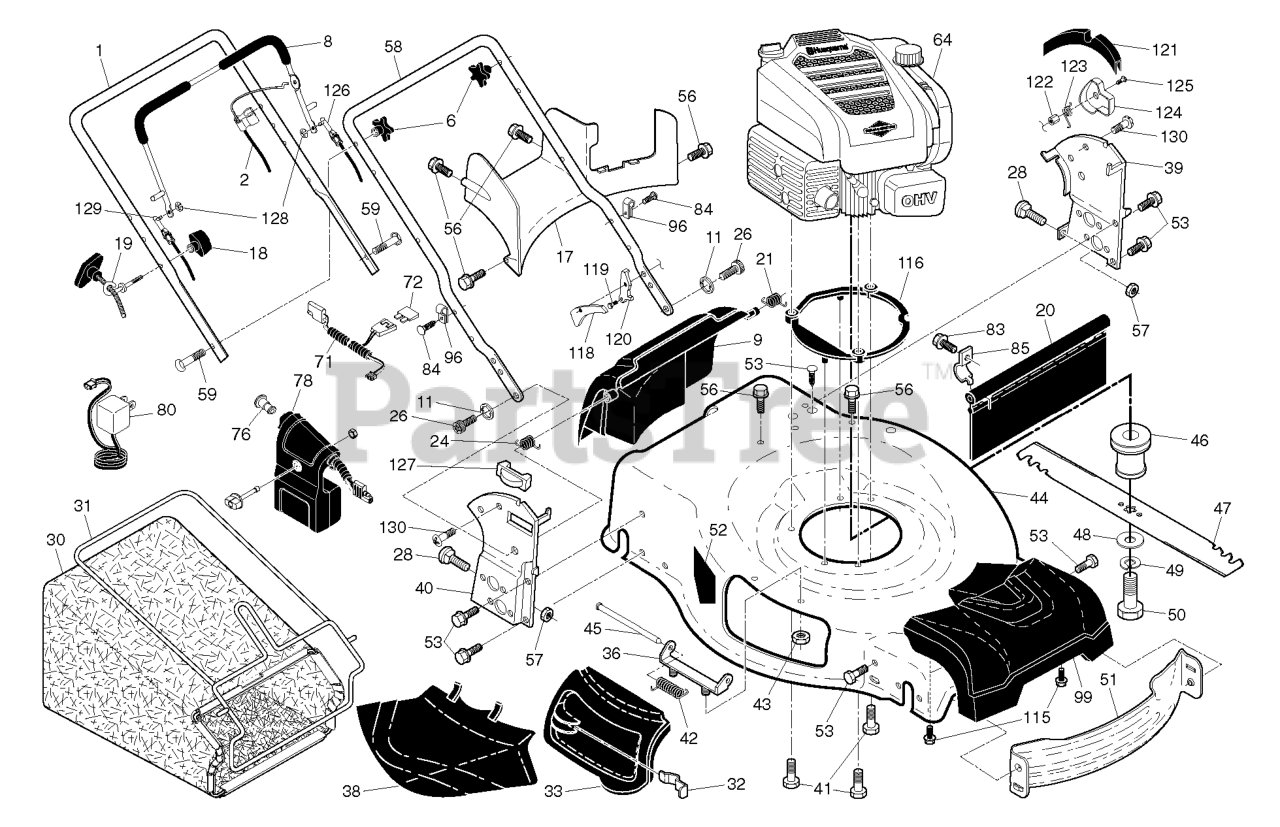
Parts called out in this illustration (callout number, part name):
1	HANDLE.UPPER.3.POS.BS.AW2.GREY
2	CABLE.MZR.RGD.22.B&S/HON.ERGO
6	KNOB.HANDLE.PLASTIC.STAR.BLACK
8	BAIL.CONTROL.MZR.ERGO.EZS.O/B
9	DOOR.REAR.ASM.22+.GEN.FG/RG.CE
11	E-RING.12MM.SHAFT
17	BAFFLE.REAR.22+RGD.AWD.PLASTIC
18	T-KNOB.NEW ROPE GUIDE
19	GUIDE.ROPE.BLK.ZINC.CHROM
20	SKIRT.REAR.22PLUS.RGD.LW(2 2MC
21	SPRING.LH.BLACK
24	SPRING.RH.GRAY
26	SCREW,DOOR/HANDLE.PIVOT
28	BOLT.CARRIAGE.LN.5/16-18X.5/8
30	GBAG.B561029EM.GRY/SILV
31	FRAME.GBAG.22+.BLK
32	LATCH.DOOR.ZINC
33	DOOR.MULCH.22 PLUS.HUSQ.GREY
36	BRACKET.ASM.HINGE.21.FWGD.
38	DEFLECTOR.CLIPPING.22.BLACK
39	BRACKET.ASM.HANDLE.LT.22+.498
40	BRACKET.ASM.HANDLE.RT.22+.498
42	SPRING.TORSION
43	NUT.FLANGE.1-4-20-SERR
44	KIT.HSG.22+AWD.MC.WO.668.TRI
45	ROD.HINGE.21
46	ADAPTER.BLADE.25M.B&S.AWD
47	BLADE REAPER, 22 IN RUST
48	WASHER,HARDEN
49	LOCKWASHER
50	BOLT.BLADE
51	BAFFLE.FRONT.22.PLUS
52	DECAL.INTERNATIONL.CUTFINGER
53	BOLT.5/16HEX.WHS.HD
56	SCREW.HX.13X.750
57	NUT.FLANGE.5/16
58	HANDLE.LOWER.22+EZS.498
59	BOLT, HANDLE 5/16-18X1.75
71	WIRING ASSY E-START MODULE, MO
76	BUTTON.KEY.CYLINDER.BLACK
78	STARTER.ASM.PUSH.BUTTON
80	CHARGER.BATT.12V LEAD-ACID.DOM
83	TAPPING SCREW
84	FASTENER.PUSH.O.250X0.783
85	BRACKET.SKIRT.22+.BZP
96	CLIP.CABLE.BLK
99	COVER.ASSEMBLY.FRONT.22+AWD
115	SCREW.SHOULDER.5/16X1.375
116	SPACER.AWD.B&S
118	COVER.INSIDE.LOWER.LT.EZS
119	BOLT.PAWL.M6
120	PAWL.ADJUSTMENT.EZS.LEFT
121	BRACKET.BAG.ASM.EZS.LH.BLK
122	NUT.PAWL.M6
123	SPRING.TORSION.PAWL ENG.LT
124	COVER.OUTSIDE.LOWER.EZS.LT
125	SCREW.TORX.PAN HEAD.M6-1
126	CABLE.MZR.EZS.LH.DSTR/ERGO
127	DOOR.REAR.LIFT.ASM EZS
128	E-RING.5/32.HD
129	CABLE.MZR.EZS.RH.ERGO.PB
130	SCREW.PAN.HEAD.#10
